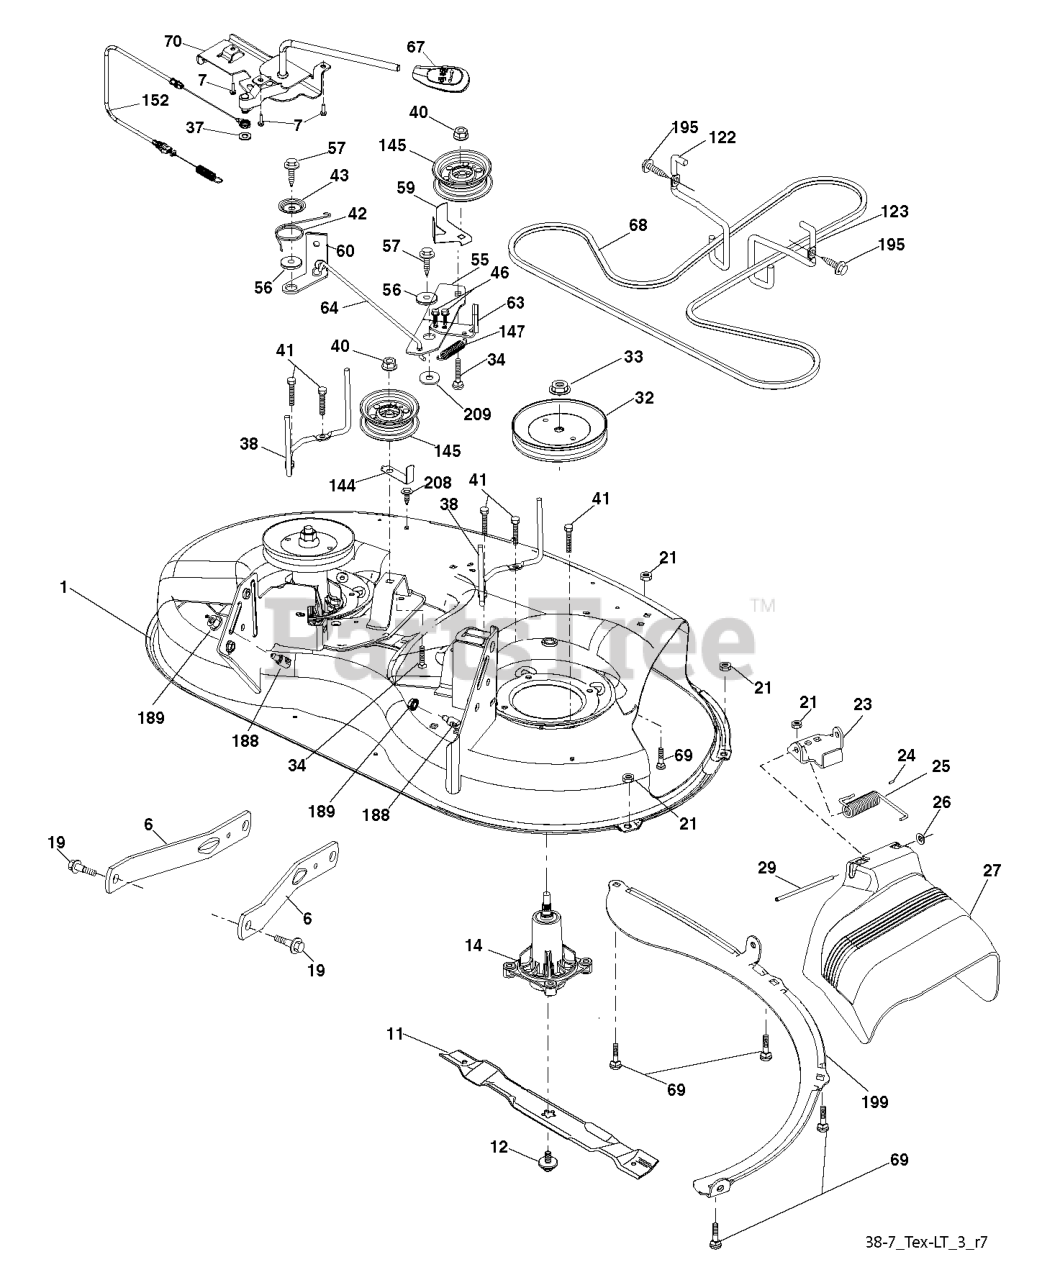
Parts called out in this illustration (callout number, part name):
1	CYLINDER
2	CYLINDER
3	PISTON ASSY
3	PISTON ASSEMBLY
4	PISTON RING
5	SUPPORT BUSHING
6	LOCKING RING
7	DECOMPRESSION VALVE
8	CYLINDER PLUG
9	SCREW MC6S 5X20
10	GASKET
12	PROTECTIVE CAP
